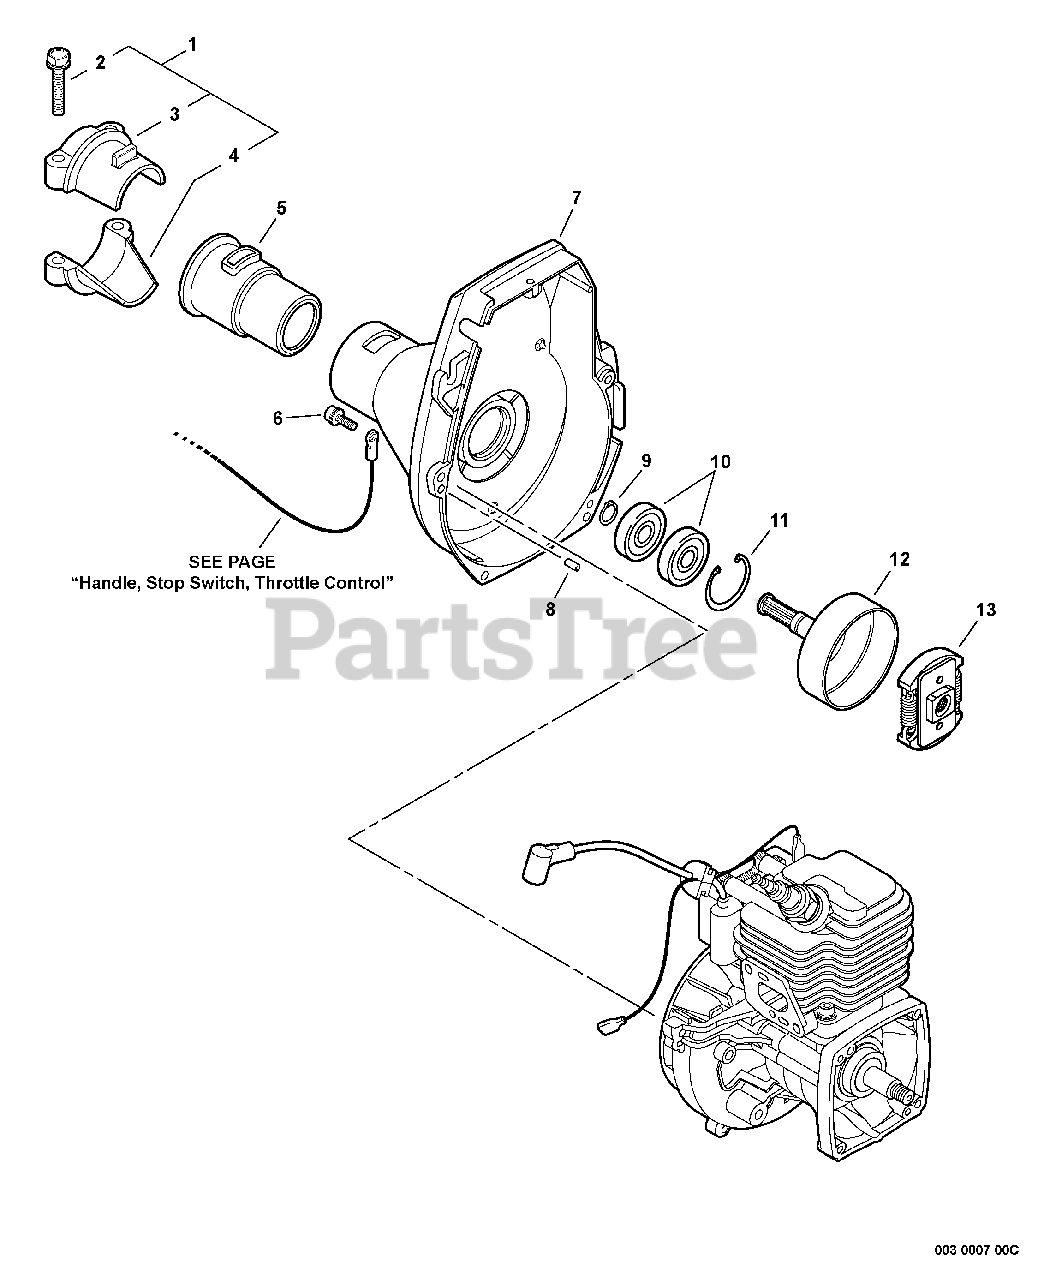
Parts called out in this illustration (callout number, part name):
1	HOLDER KIT
2	BOLT - 5X25
3	CLAMP, MAIN PIPE - UPPER
4	CLAMP, MAIN PIPE - LOWER
5	CUSHION
6	SCREW - 4X16
7	CASE, FAN
8	PIN - LOCATING
9	RING, RETAINING - 12
10	BEARING, BALL - 6001
11	RING, RETAINING - 28
12	DRUM, CLUTCH
13	CLUTCH ASSY
